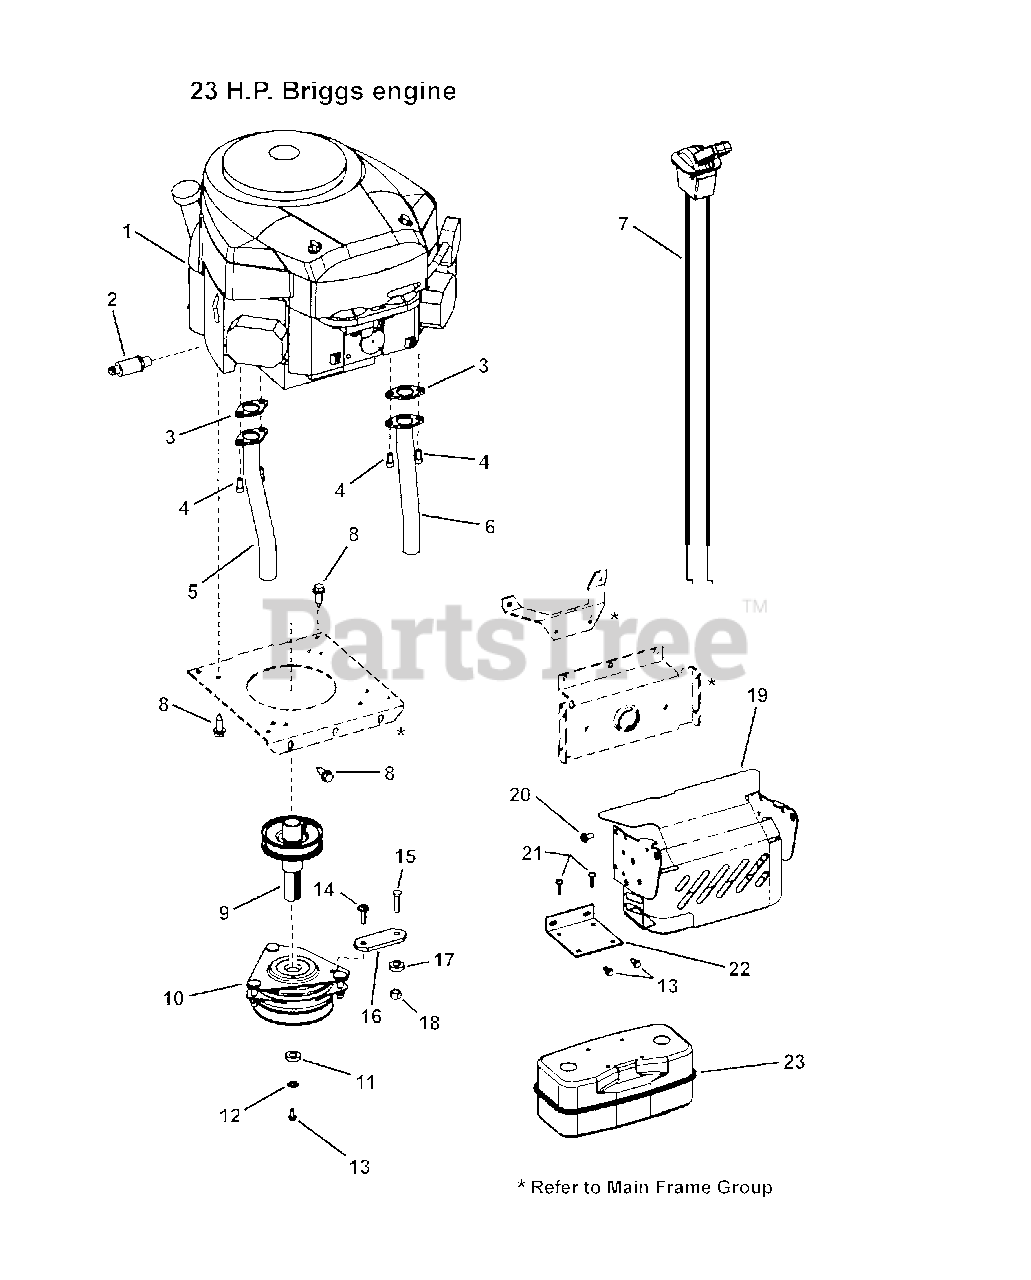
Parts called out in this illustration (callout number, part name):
2	ASSEMBLY, Oil Valve
3	GASKET, Exhaust B&S Reg. (No Chre.)
4	SCREW, 5/16-18 x 5/8" Torx Head, YZ
5	EXHAUST TUBE RH
6	EXHAUST TUBE LH
7	THROTTLE ASSY, Dual Lever
8	SCREW, 3/8-16 x 1-1/4" Hex Head Self-Tap
9	ADAPTER - Electric PTO
10	CLUTCH, Electric (Ogura GT-EH13)
11	WASHER, .468 ID x 1.38 OD x .25 Flat
12	WASHER, 7/16 Split Lock
13	SCREW, 1/4-20 x 5/8" Hex Washer Self-Tap
14	SCREW, 5/16-18 x 7/8" Pan Head Self-Tap, Torx, BP
15	SCREW, 5/16-18 x 3/4" Hex Head Cap
16	ANCHOR PAD, Clutch
17	WASHER, .34 x .69 x .08 Flat
18	NUT, 5/16-18 Hex Nyloc
19	ASSY - Heat Shield
20	SCREW, 5/16-18 x 1/2" Hex Washer Head
21	SCREW, 1/4-14 x 3/8" Hex Washer Self-Tap
22	BRACKET - Muffler
23	MUFFLER, Twin
